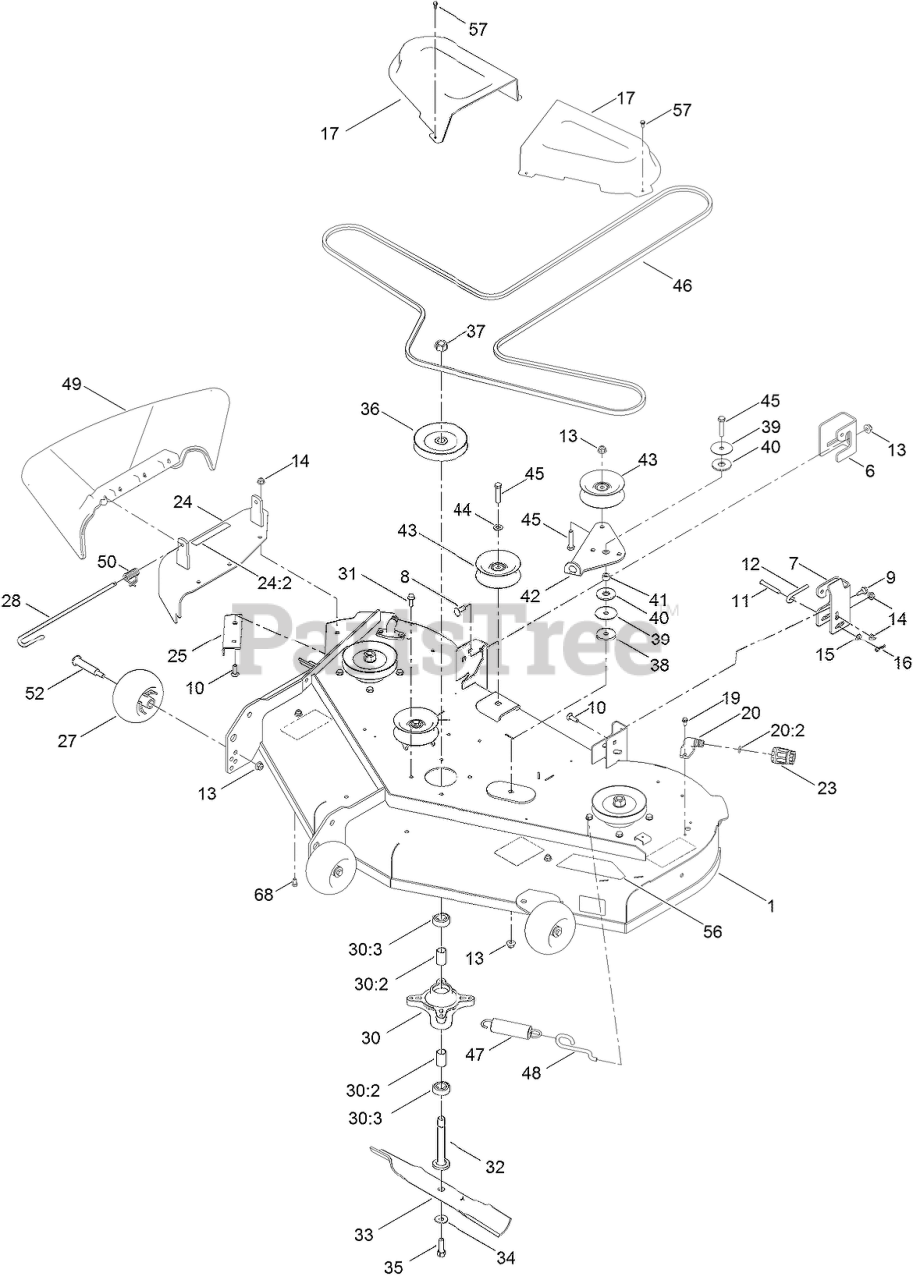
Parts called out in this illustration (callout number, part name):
1	DECK AND DECAL ASM
6	BRACKET-HANGER, RH
7	BRACKET-HANGER, LH
8	BOLT-CARR
9	SCREW-SHOULDER,HWH
10	SCREW-CARR
11	PIN-CLEVIS
12	ROD-LEVEL, DECK
13	NUT-HF, NI
14	NUT-HF, NI
15	WASHER-PLAIN
16	PIN-COTTER
17	COVER-BELT
19	SCREW-HWH
20	FITTING-WASHOUT
20:2	O-RING
23	CONNECTOR-HOSE
24	COVER ASM W/DECAL
24:2	DECAL-DANGER
25	BAFFLE-CUTOFF
27	ROLLER-SCALP, ANTI
28	PIN-CHUTE
30	SPINDLE ASM
30:2	SPACER
30:3	BEARING-BALL
31	SCREW-TAPTITE
32	SHAFT-SPINDLE
33	BLADE-HI LIFT
34	WASHER-BELLEVILLE
35	SCREW-HH
36	PULLEY
37	NUT-HEX
38	WASHER-PLAIN
39	WASHER
40	WASHER-FRICTION, COMPOSITE
41	SPACER
42	ARM-IDLER
43	PULLEY-IDLER, FLAT
44	WASHER-FLAT
45	SCREW-HH
46	BELT-V
47	SPRING-EXTENSION
48	HOOK-RETURN, SPRING
49	DEFLECTOR-DISCHARGE
50	SPRING-TORSION
52	BOLT-SHOULDER
56	DECAL-DECK
57	SCREW-TAPTITE
68	SCREW-HH
